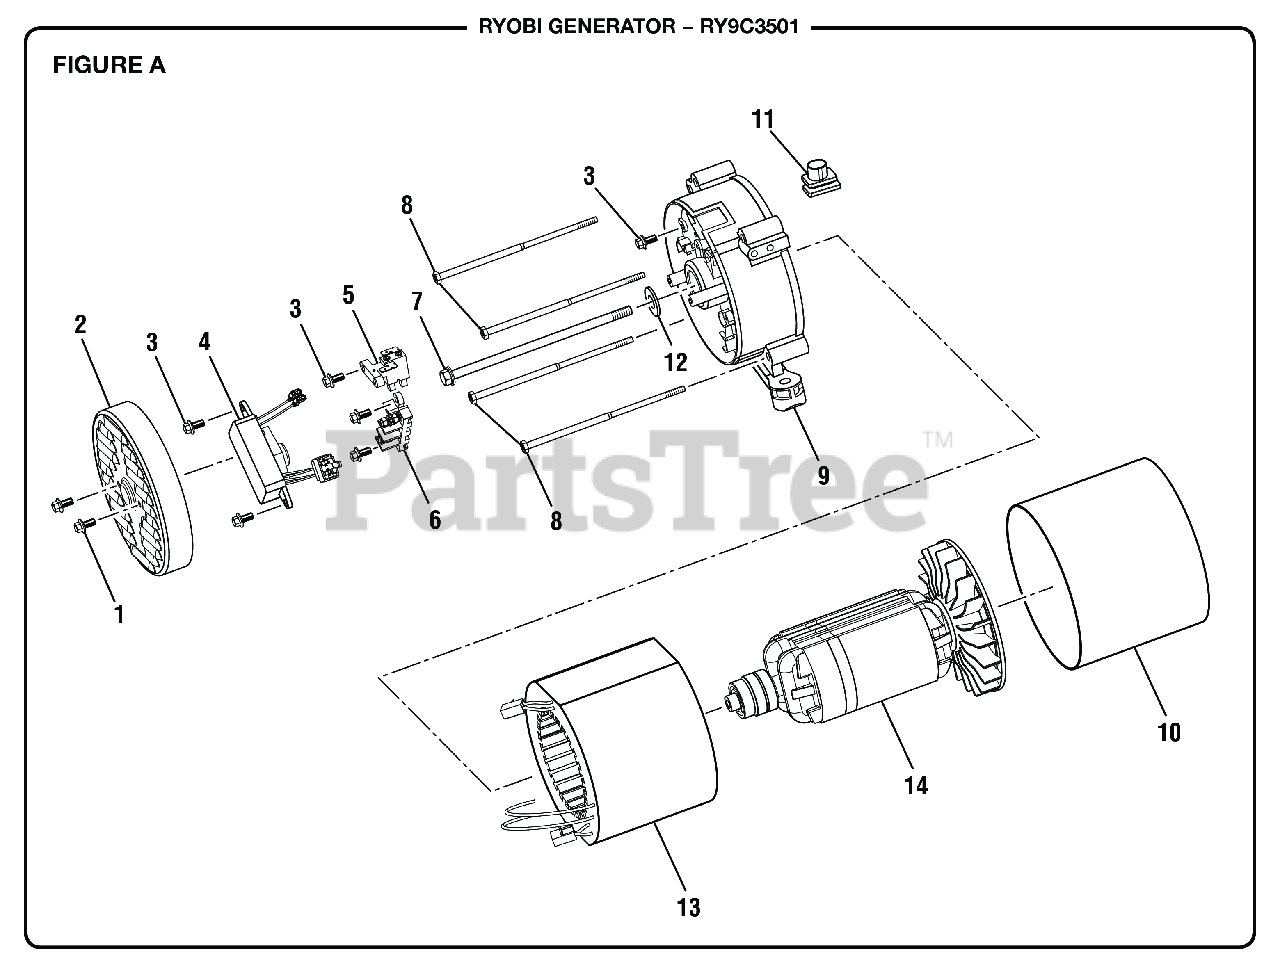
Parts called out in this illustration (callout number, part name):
1	Bolt (M5 x 12 mm, Hex Flange Hd.)
2	Generator Head Cover
3	Bolt (M5 x 16 mm, Hex Flange Hd.)
4	Automatic Voltage Regulator
5	Brush Assembly
6	Terminal Block
7	Rotor Bolt
8	Stator Bolt
9	Bearing Housing
10	Generator Head Cover
11	Rubber Wire Protector
12	Lock Washer (Rotor)
13	Stator Assembly
14	Stator Assembly
